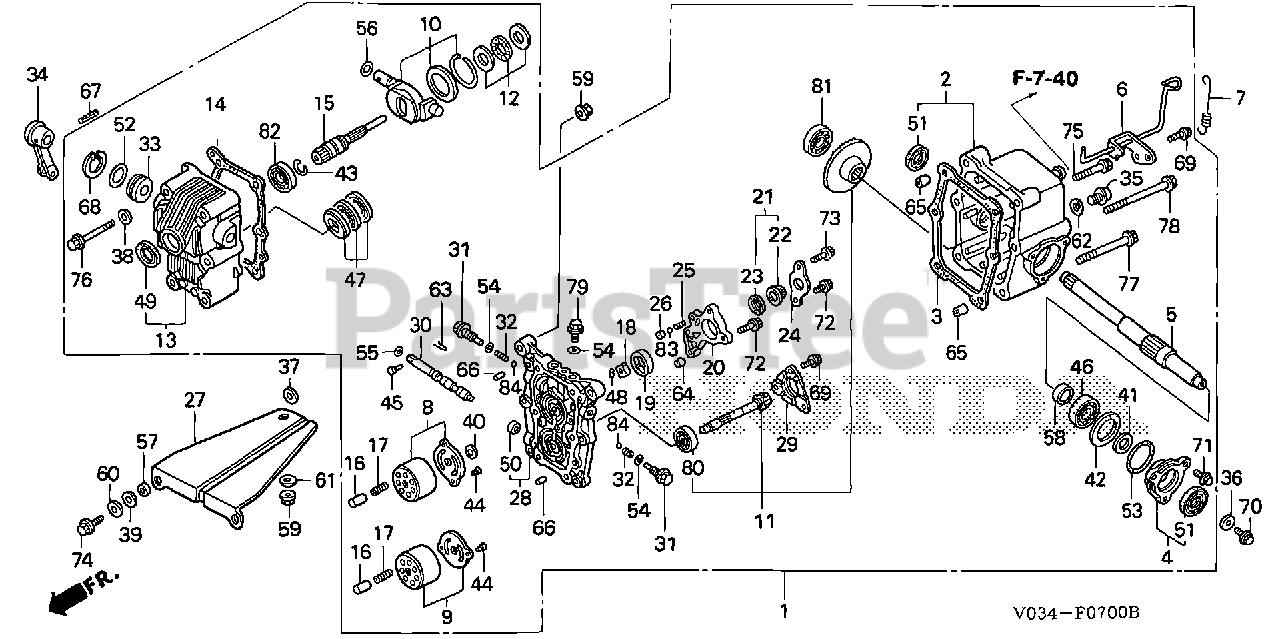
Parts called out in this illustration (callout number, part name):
1	TRANSMISSION ASSY.
2	CASE, RR. TRANSMISSION
3	GASKET, RR. TRANSMISSION CASE
4	HOLDER, OIL SEAL
5	SHAFT, CROSS
6	ARM, NEUTRAL VALVE
7	SPRING, NEUTRAL VALVE
8	PLATE SET, PUMP CYLINDER
9	PLATE SET, MOTOR CYLINDER
10	BOWL SET, CONTROL
11	GEAR SET, MOTOR SHAFT & BEVEL
12	BEARING SET, THRUST NEEDLE
13	CASE, PUMP
14	GASKET, PUMP CASE
15	SHAFT, PUMP
16	PISTON, PUMP (HOLE DEPTH=18MM)
17	SPRING, PISTON (5.8X34.5)
18	ROTOR, TROCHOID
19	VANE, TROCHOID
20	HOUSING, TROCHOID
21	FILTER ASSY., SUCTION
22	FILTER, SUCTION
23	SEAL, RUBBER
24	PLATE, FILTER CAP
25	SPRING, RELIEF VALVE
26	SEAT, RELIEF VALVE
27	PLATE, TRANSMISSION MOUNTING
28	PLATE, DISTRIBUTOR
29	HOLDER, BEARING
30	SPOOL, NEUTRAL VALVE
31	BOLT, CHECK VALVE
32	SPRING, CHECK VALVE
33	BUSH, CONTROL BOWL (B)
34	ARM, CLUTCH
35	BOLT, PLUG
37	WASHER (8MM)
38	WASHER, SEALING (9X16X1.5)
39	WASHER, WAVE (12MM)
40	WASHER, THRUST (8MM)
41	WASHER, PLAIN (15MM)
42	SHIM A, BEVEL GEAR (1.5MM)
42	SHIM B, BEVEL GEAR (1.55MM)
42	SHIM C, BEVEL GEAR (1.6MM)
42	SHIM D, BEVEL GEAR (1.65MM)
42	SHIM E, BEVEL GEAR (1.7MM)
42	SHIM F, BEVEL GEAR (1.75MM)
43	CLIP, BEARING
44	PIN, DOWEL (3X5.8)
45	PIN, NEUTRAL VALVE
46	BEARING, RADIAL BALL (6904) (NTN)
47	BEARING, THRUST BALL (51204)
48	ROLLER (2.5X11.8)
49	OIL SEAL (17X30X5) (NOK)
50	DUST SEAL (9X15X5)
51	OIL SEAL (15X28X7)
52	O-RING (25X2.4)
53	O-RING (34.6X1.9)
54	O-RING (11X1.9)
55	O-RING (5.8X1.9)
56	O-RING (11.8X1.9)
57	COLLAR, TRANSMISSION MOUNT (8X12X4.7)
58	COLLAR, BEVEL GEAR
59	NUT, FLANGE (8MM)
60	WASHER, PLAIN (8MM)
61	WASHER, PLAIN (8MM)
62	WASHER, DRAIN PLUG (14MM)
63	PIN, LOCK (4MM)
64	PIN, DOWEL (8X10)
65	PIN, DOWEL (10X12)
66	PIN, DOWEL (5X8)
67	PIN, SPRING (4X28)
68	CIRCLIP (INNER) (30MM)
69	BOLT, FLANGE (6X12)
70	BOLT, FLANGE (6X16)
71	BOLT, FLANGE (6X16)
72	BOLT, FLANGE (6X25)
73	BOLT, FLANGE (6X32)
74	BOLT, FLANGE (8X40)
75	BOLT, FLANGE (8X45)
76	BOLT, FLANGE (8X65)
77	BOLT, FLANGE (8X70)
78	BOLT, FLANGE (8X90)
79	BOLT, FLANGE (10X16)
80	BEARING, RADIAL BALL (6001)
81	BEARING, RADIAL BALL (6002)
82	BEARING, RADIAL BALL (6003)
83	BALL, STEEL (#6) (3/16)
84	BALL, STEEL (#8) (1/4)
